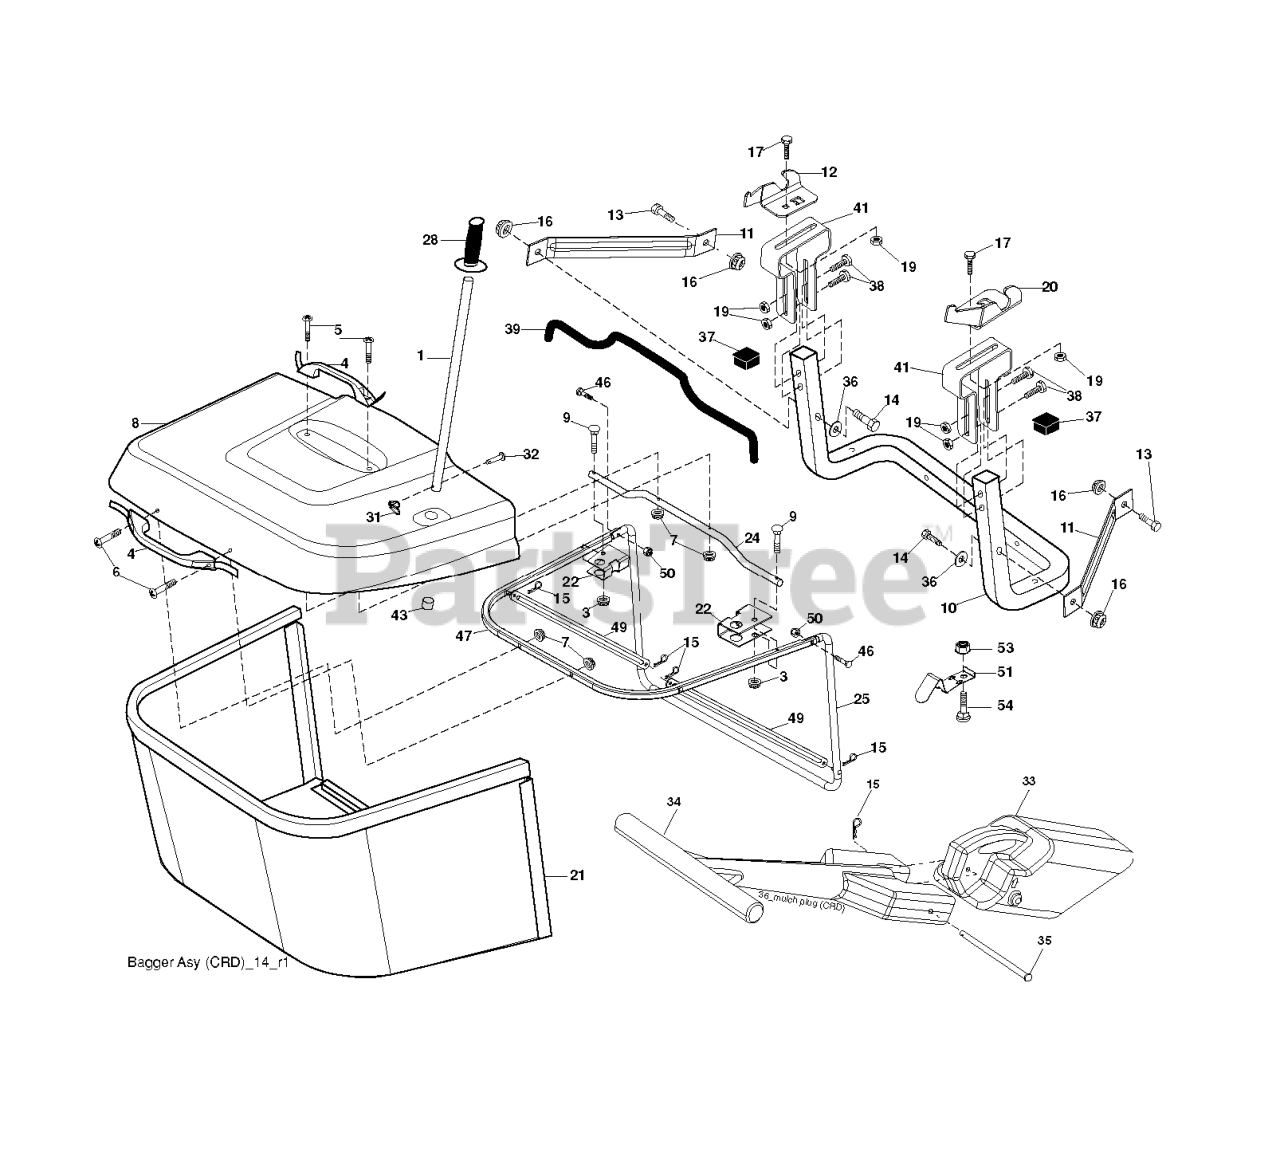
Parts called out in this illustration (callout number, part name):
1	TUBE HANDLE
3	NUT T
4	HANDLE.BAGGER.W/LVRS.BLK.CRD
5	SCREW.PAN.HEAD
6	REPL BY 532 75 00-29
8	COVER.PNT.BGR.CRD.WSLOTS.MS668
9	Bolt Carriage 1/4-20 x 2.25d x Gr.5
10	TUBE
11	BRACKET.SUPPORT.UPPER.BAG.CRD
12	BRKT PIVOT
14	BOLT-HEX EAK
15	RETAINER-SPRNG RB
16	NUT LOCK FLG 3/8-16 UNC
17	RP BOLT 5/16-18 X3/4 ZN/YEL GR
19	NUT LOCK HEX FLANGE 5/16-18
20	BRKT.PIVOT.RH.CRD
21	BAGGER.ASM.CRD.2007
22	BRKT.SIDE.BAG.CRD
24	TUBE.PIVOT.BAG.CRD.BLACK
25	PIPE
28	GRIP.HANDLE.BLACK
31	RETAINER CLIP
32	RIVET,DRILLED
33	PLUG.MULCHER.92 CRD
34	HANDLE.MULCHER.92.CRD (2 2)
36	WASHER
37	Plug Support Bagger CRD
38	BOLT.5/16-18X2.5
39	SEAL.BAGGER.CRD
41	BRKT.VERT.ADJ.BAGGER.CRD
43	PLUG, TUBING END
46	BOLT.CARRIAGE.5/16-18
47	PIPE
49	ROD
51	LATCH
53	NUT
54	BOLT
